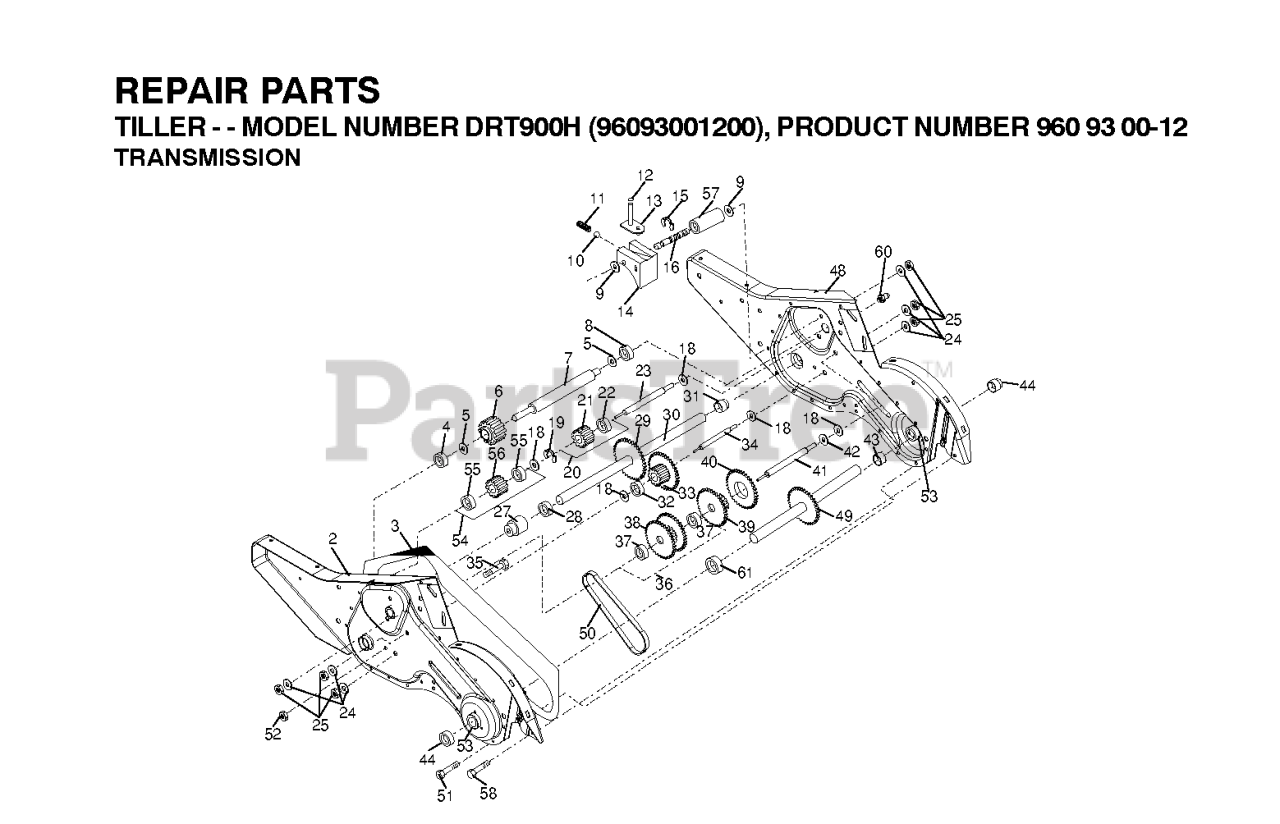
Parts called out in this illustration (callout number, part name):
1	TRANSMISSION.ASM.17
2	GEARCASE.ASM.DRT.LH.
3	GASKET.GEARCASE.CRT/DRT.TILLER
4	NEEDLE BRNG LT
5	THRUST WASHER
6	GEAR.PINION.INPUT.DRT
7	SHAFT.INPUT.D.9TEETH
9	WASHER, SEAL (2 2)
10	BALL, STEEL
11	SPRING-SHIFT CRT
13	BRACKET ASM.SHIFT.CRT
14	SHIFT FORK TI
16	SHAFT.SHIFT.DRT
20	GEAR ASSY CRT
21	GEAR-REV IDLR CRT
22	NEEDLE BEARING TI
23	SHAFT.IDLER.REVERSE.CRT
24	LOCKWASHER
25	NUT.ASF.HEX.7/16
27	BEARING, SHAFT, GROUNDDRIVE LH
30	GROUND SHAFT ASS'Y
31	BEARING, SHAFT RH CRT
33	SPRCKT 8 GEAR CRT
34	SHAFT.SECONDARY.REDUCTION.CRT
35	SCRW WHIZ LOK CRT
36	GEAR & SPROCKET.ASM.WBEARIN
37	BEARING.NEEDLE.CRT
38	ASM.GEAR & SPROCKET
39	GEAR.CLUSTER.DRT.TILLER
41	SHAFT.REDUCTION.FIRST.DRT
42	BRNG RACE T
44	SEAL ASM, OIL
48	GEARCASE.ASM.DRT.RH.
49	SHAFT.ASM.TINE
50	CHAIN.TILLER
51	SCREW
53	KIT.BEARING.TILLER.
54	GEAR.ASM.DRT.TILLER
55	BEARING.NEEDLE
56	GEAR.DRT.IDLER
57	SPACER.SPLIT
58	BOLT SHOULDER 1/4-20 UNC X.875
60	FITTING.GREASE.TAPERED
61	SPACER.1.015X1.50X.650
61	GREASE CARTRIDGE
